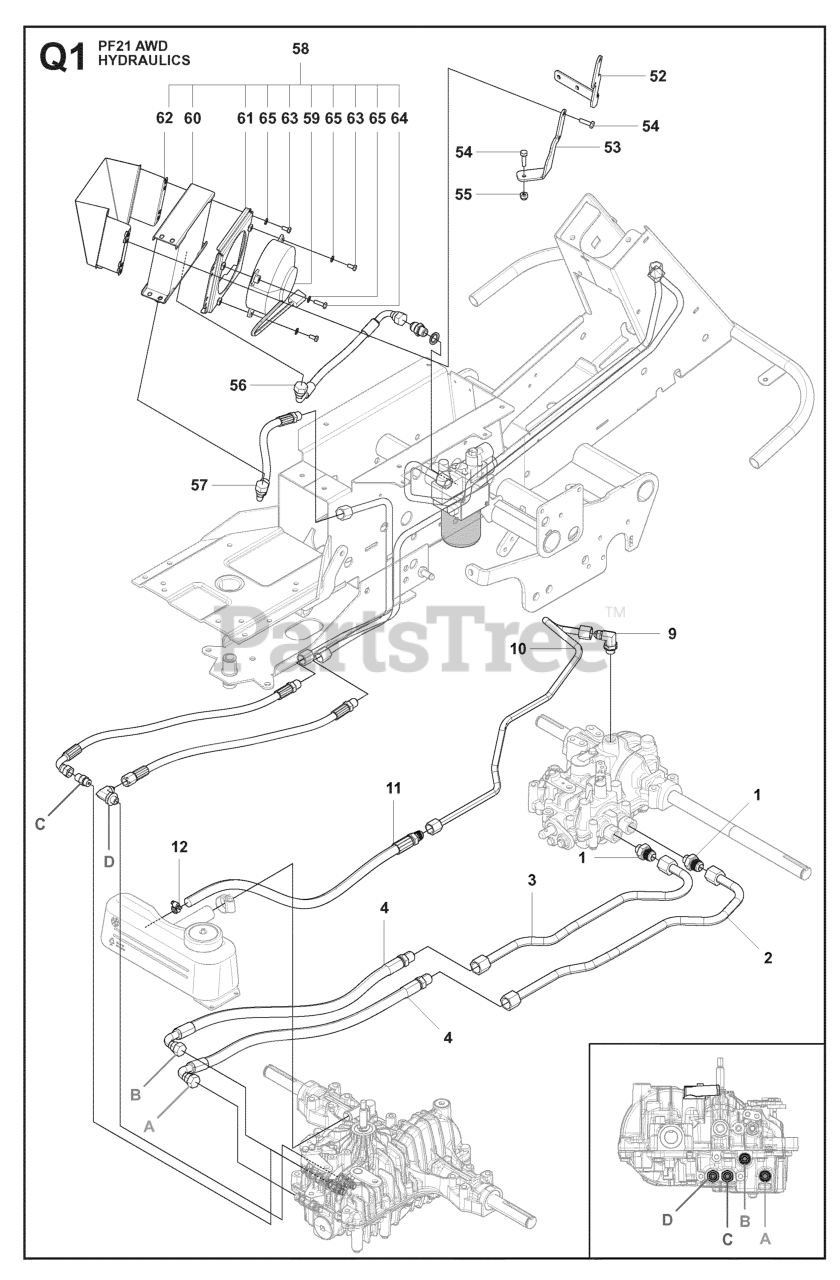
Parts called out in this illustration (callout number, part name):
1	PIPE FITTING
51	HOSE GUARD D=43 L=400
54	SCREW EHHFM
55	LOCKNUT M6
65	WASHER - M6
